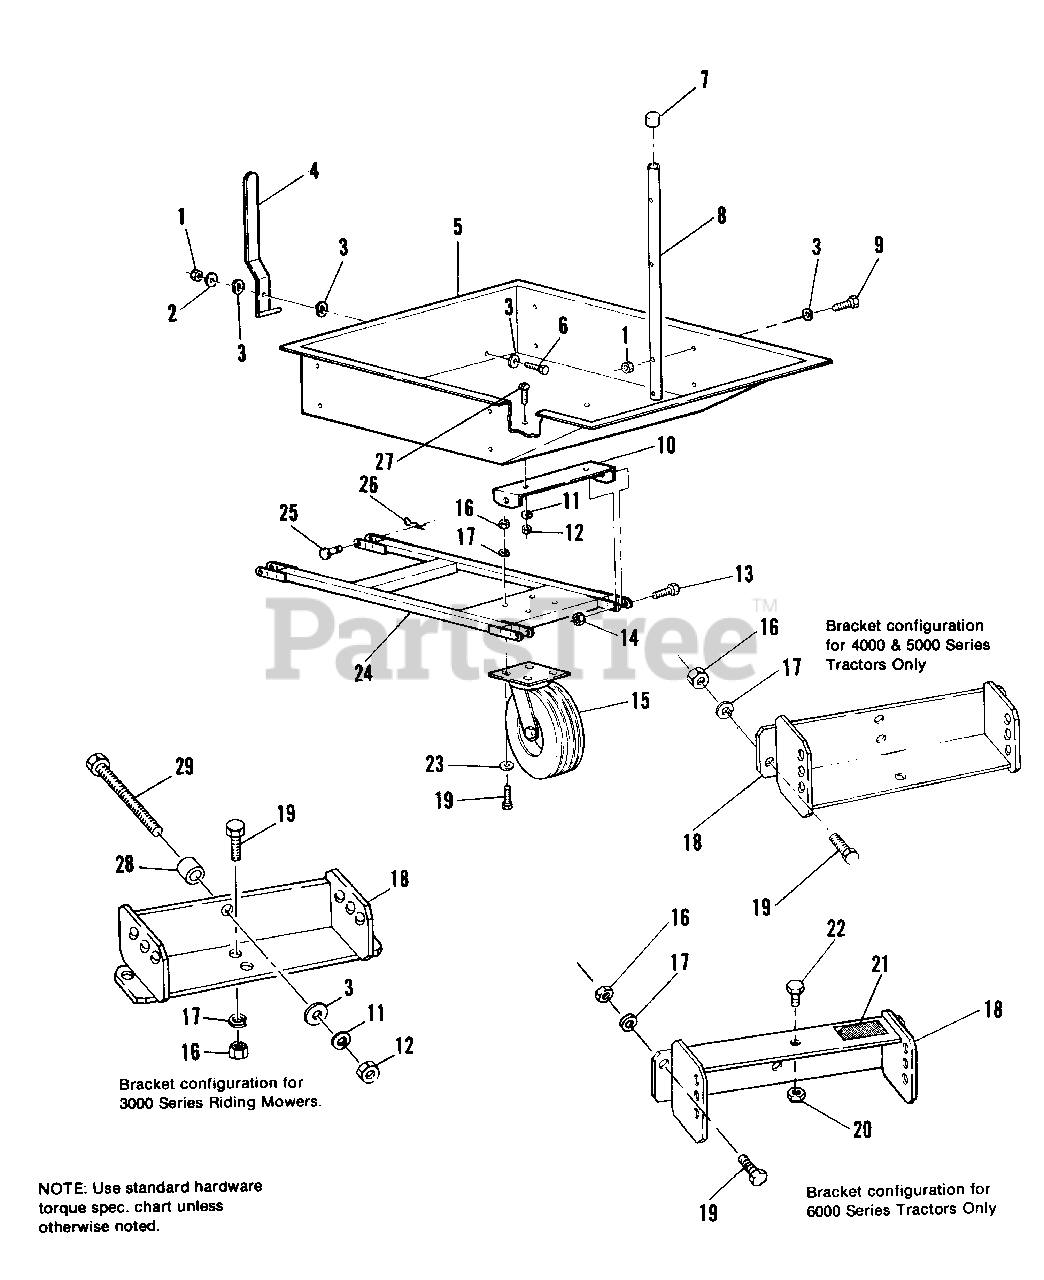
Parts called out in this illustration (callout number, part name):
1	NUT, Hex Lock, 5/16-18
2	WASHER, Spring, 5/16
3	WASHER, Plain, 5/16
4	HANDLE, Latch
5	CART, Box
6	CAPSCREW, Hex Hd., 5/16-18 x 1, Gr. 5
7	CAP, Plastic
9	CAPSCREW, Hex Hd., 5/16-18 x 1-1/2, Gr. 5
10	"U" Bracket
11	LOCKWASHER
12	NUT, Hex, 5/16-18
13	CAPSCREW, Hex Hd., 1/2-13 x 1-1/4, Gr. 5
14	NUT, Hex Lock, 1/2-13
15	WHEEL ASSY., Swivel
16	NUT, Hex, 3/8
17	LOCKWASHER, 3/8
18	*BRACKET, Rear Hitch
19	CAPSCREW, Hex Hd., 3/8-16 x 1, Gr. 5
20	NUT, Hex Full Lock, 3/8-16 (6000 Tractors only)
21	DECAL, Warning (6000 Tractors Only)
22	CAPSCREW, Hex, 3/8-16 x 3/4 (6000 Tractors only)
23	WASHER, Plain, 3/8
24	"H" Frame
25	PIN, Clevis, 1/2 x 1-1/4
26	HAIR PIN
27	CARRIAGE BOLT, 5/16-18 x 3/4, Gr. 5
28	SPACER, 3/8", Hitch Bracket (1691094 only)
29	HEX BOLT, 5/16-18 x 2-1/2 (1691094 Only)
